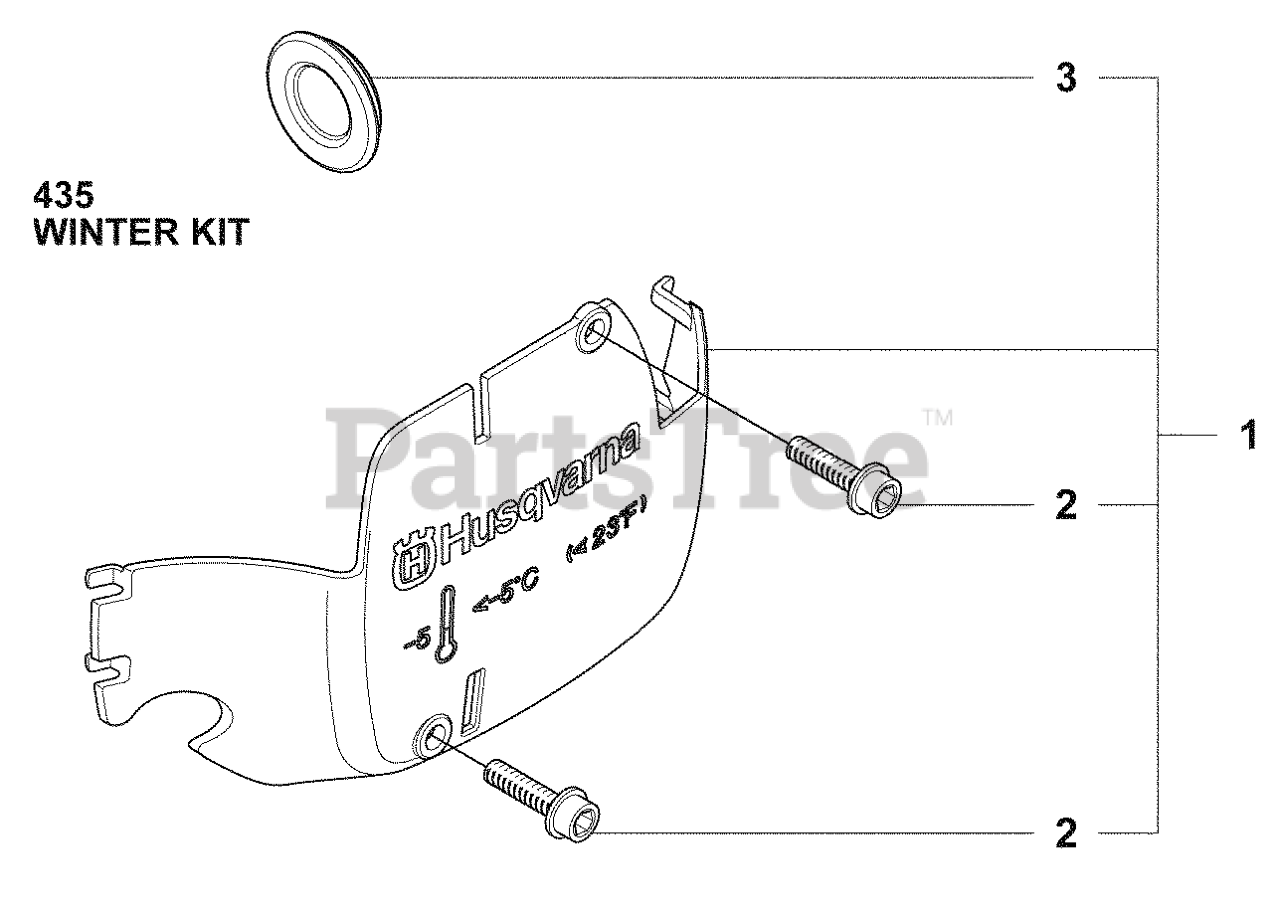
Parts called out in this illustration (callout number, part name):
1	WINTER KIT
2	SCREW
3	PLUG
